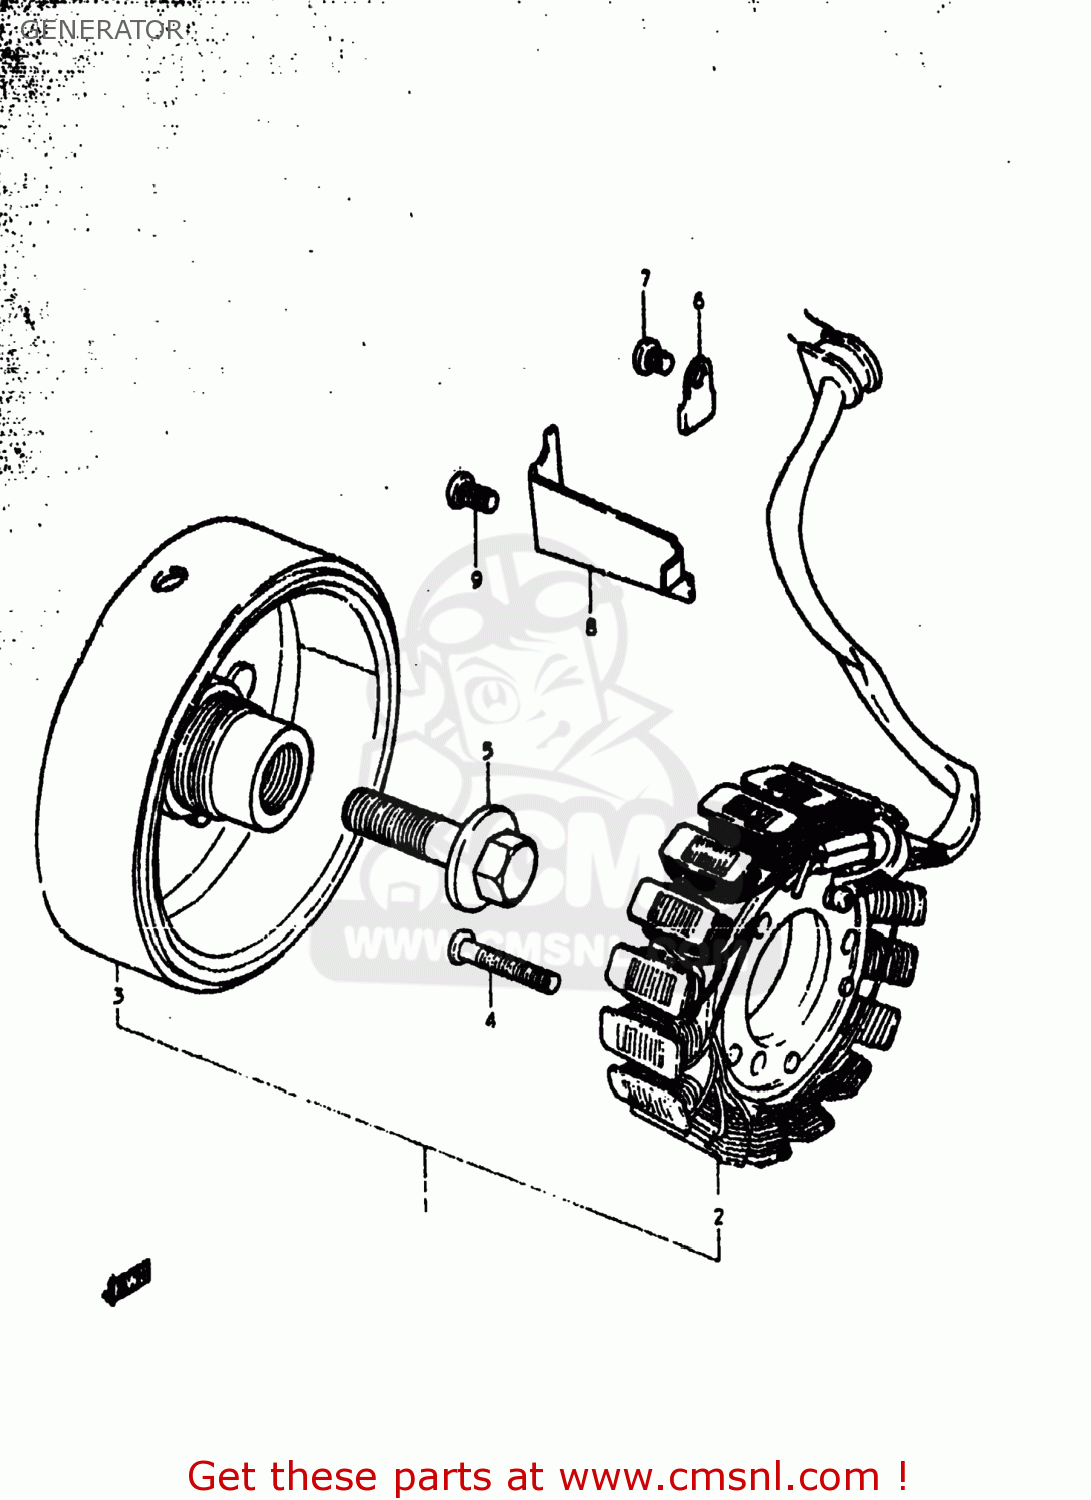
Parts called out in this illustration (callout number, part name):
1	GENERATOR ASSEMBLY
2	STARTER ASSY
3	ROTOR ASSEMBLY
4	SCREW
5	BOLT
6	CLAMP,GENERATOR LEAD WIRE
7	SCREW
8	CLAMP,GENERATOR LEAD WIRE
9	SCREW
